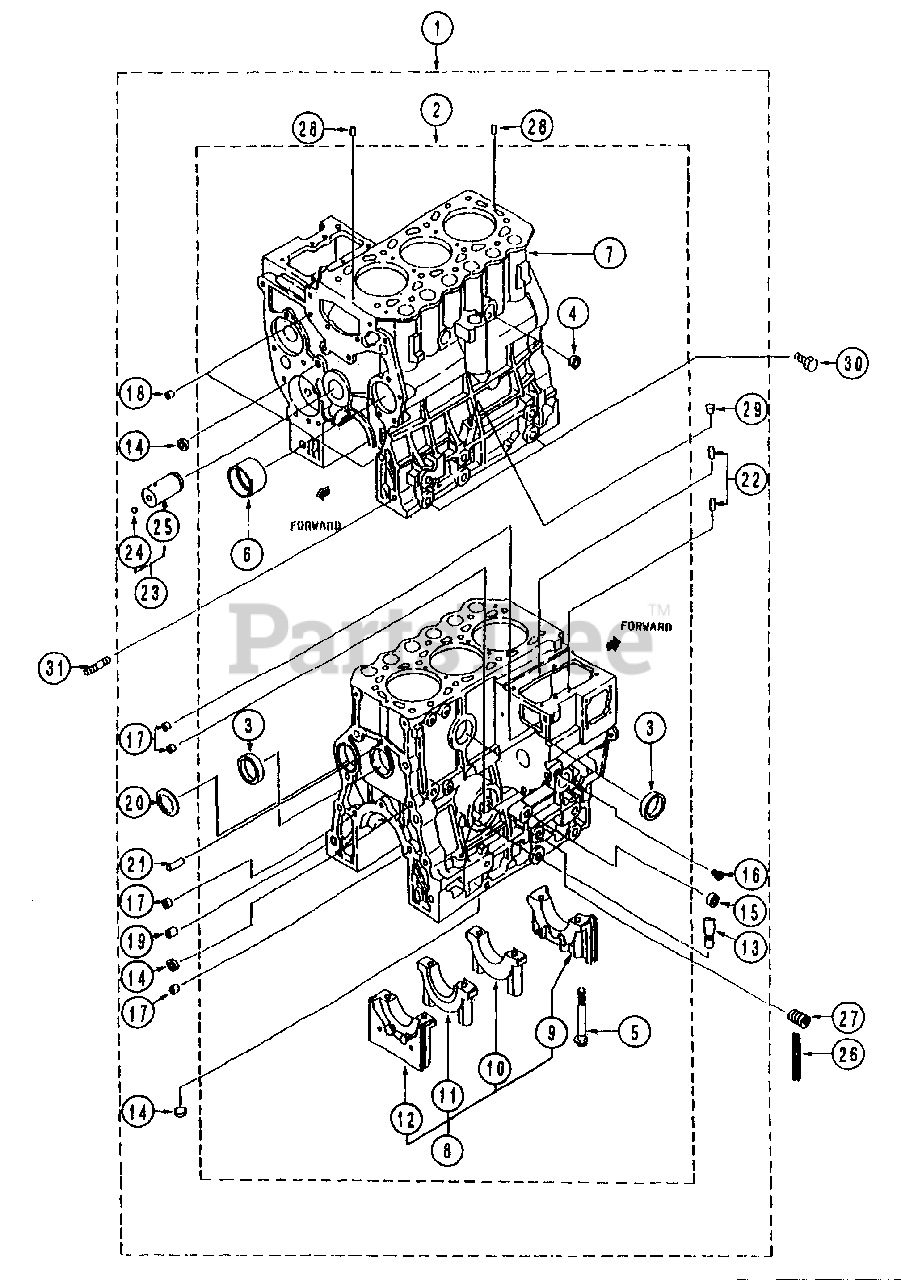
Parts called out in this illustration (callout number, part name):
1	Block Ass'y, Cylinder
2	Block Sub Ass'y, Cyl.
3	Cap, Sealing
4	Cap, Sealing
5	Bolt, Bearing Cap
6	Bush, Camshaft
7	Block, Cylinder
8	Cap Set, Metal
9	Cap, Metal Front
12	Cap, Metal Rear
13	Retainer, Oil lever
14	Cap, Sealing (12)
15	Cap, Sealing
16	Plug, Taper
17	Bushing, Knock
18	Bushing, Knock
19	Bushing, Knock
20	Plug,Expansion
23	Shaft Ass'y, Idler
25	Shaft, Idler
27	Shaft, Oil Filter
29	Plug, Taper
